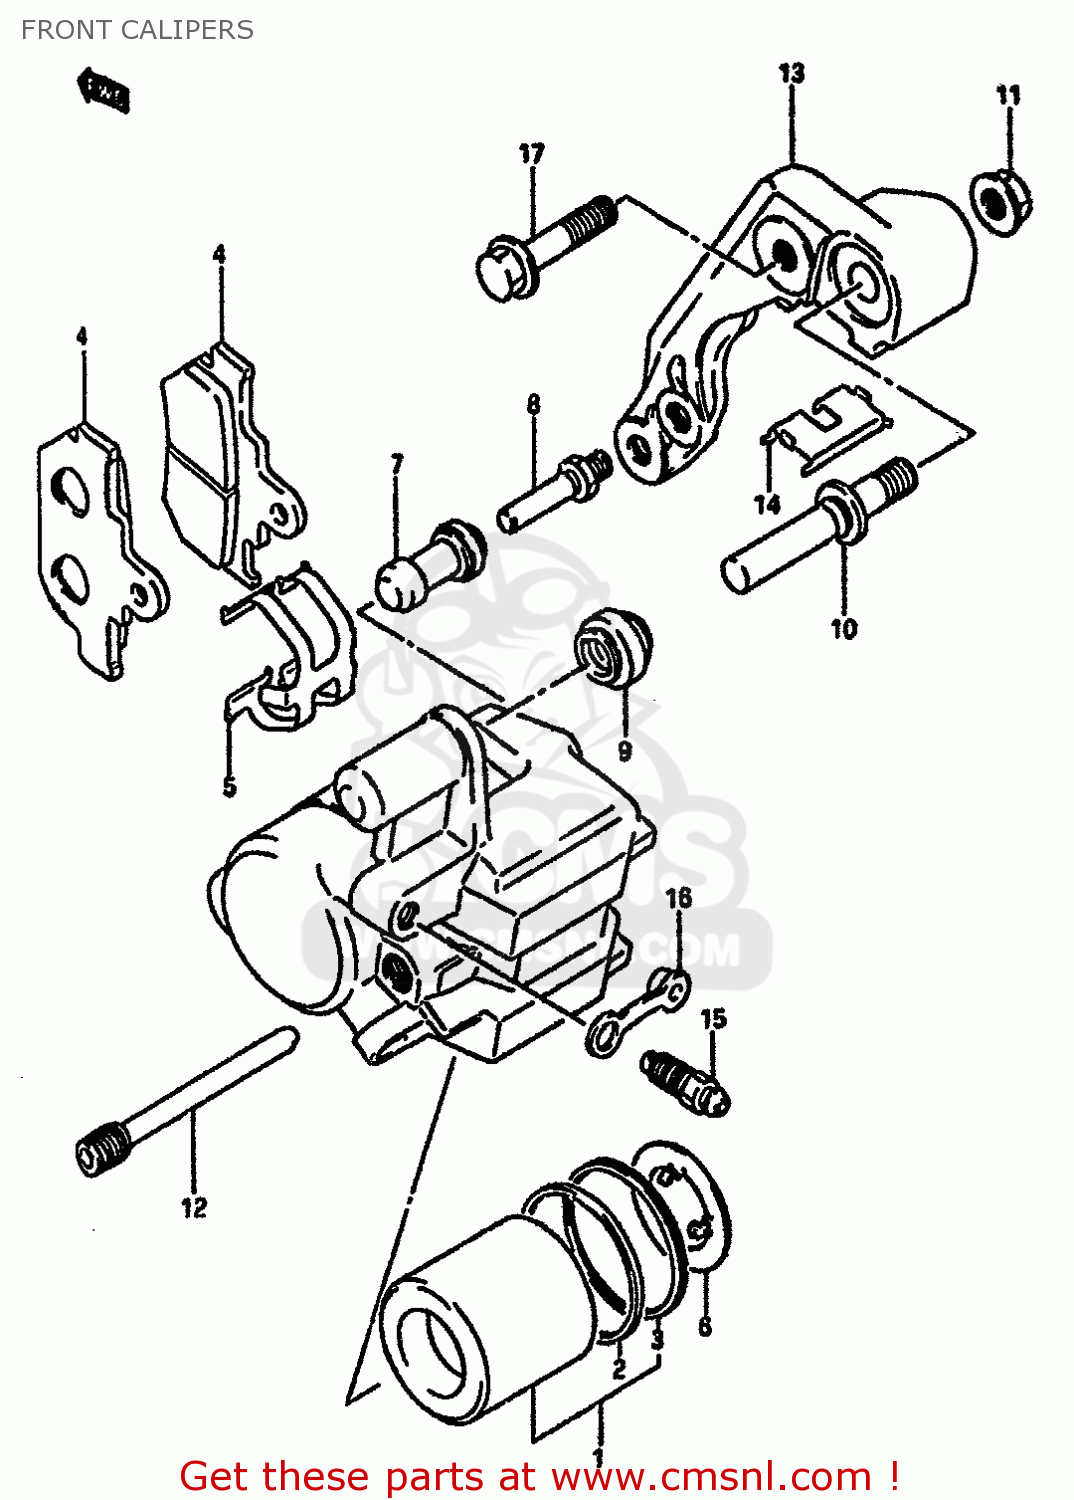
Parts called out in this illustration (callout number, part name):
1	PISTON SET,CALIPERS
2	SEAL,PISTON
3	DUST SEAL,PISTON
4	PAD
5	SPRING,PAD
6	SHIM
7	BOOT
8	PIN,BOLT
9	BOOT
10	PIN,SLIDE
11	NUT,SLIDE PIN
12	PIN,HANGER
13	BRACKET
14	RETAINER
15	BLEEDER
16	CAP,BLEEDER
17	BOLT(8X35)
